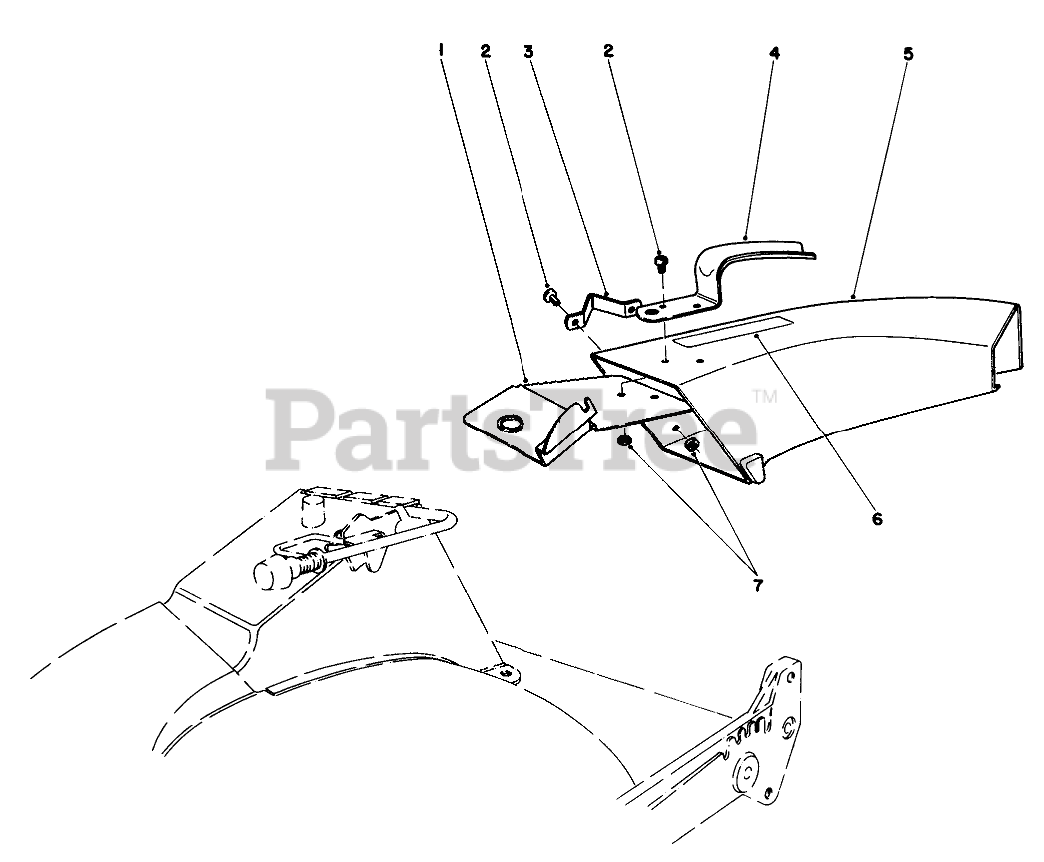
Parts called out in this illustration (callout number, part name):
1	Plate-Discharge Chut
2	10-24 X 5/8 PAN HD MS
3	SIDE BRACKET
4	CHUTE HANDLE
5	Chute Assembly (Incl. Ref. #1-6)
6	DECAL CAUTION
7	NUT-LOCK, NI
